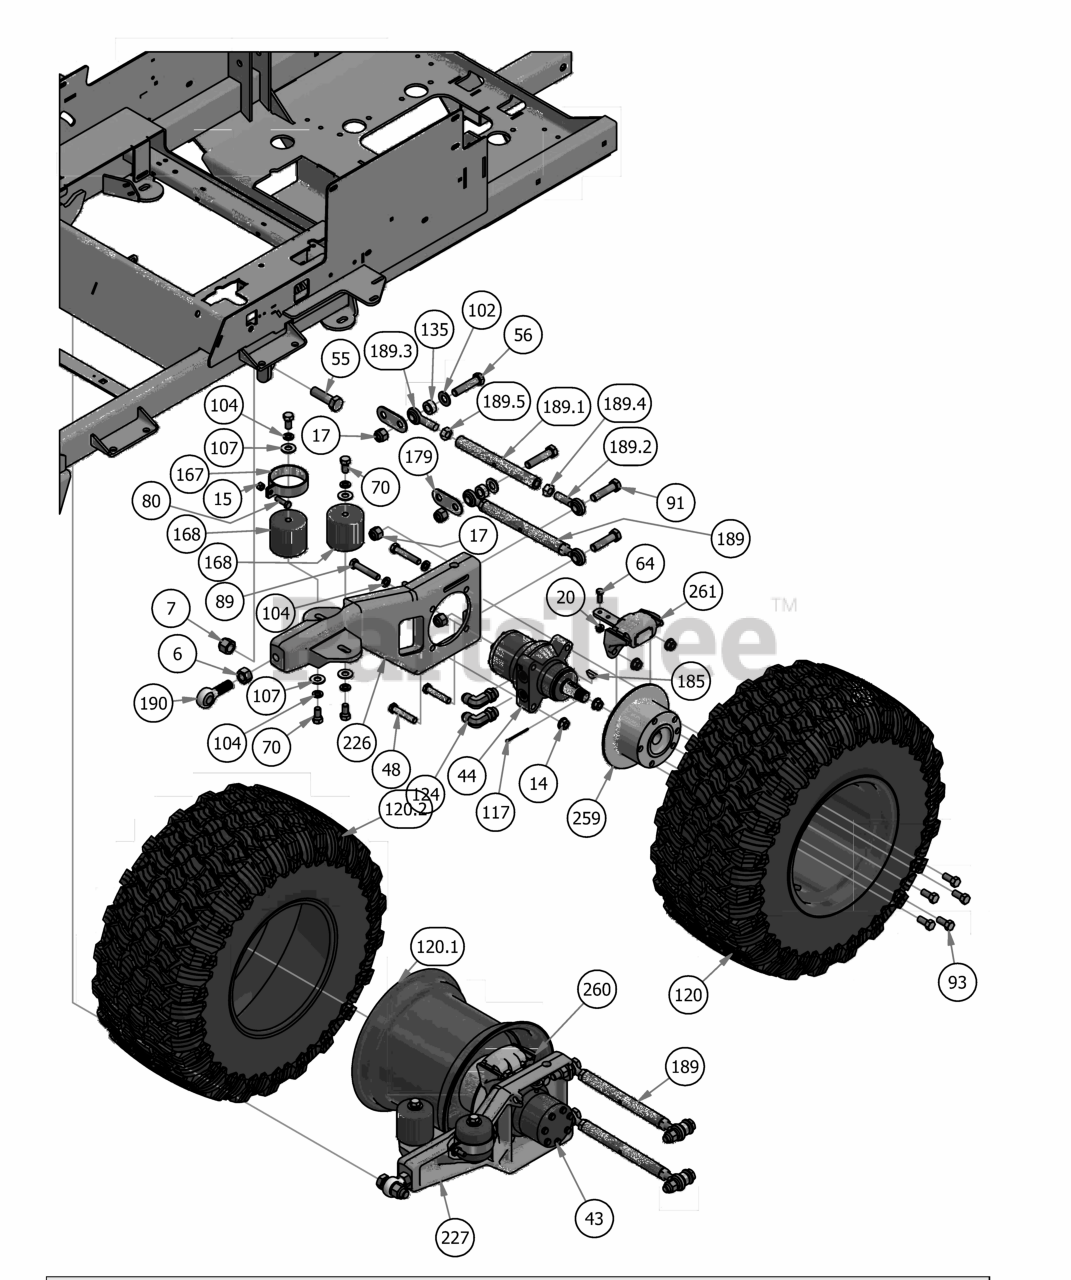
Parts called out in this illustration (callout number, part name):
6	3/4"-16 Fine Full Nut
7	3/4" Course Thread Nylon Lock Nut
14	1/2" Flange Nut
15	3/8" Hex Nut
17	5/8 Std NC Nylock Nut
20	5/16-18 Nylon Flange Nut
43	18ci Parker Wheel Motor-Right
44	18ci Parker Wheel Motor - Left
48	1/2" x 3" Hex Bolt
55	3/4 x 2 1/2 Course Thread Bolt
56	AS 2465 - 5/8 x 2 3/4 UNC
64	5/16" x 1" Bolt
70	1/2" x 1" Hex Bolt
80	3/8" x 1 1/4" Hex Bolt
89	1/2" x 2 3/4" Hex Bolt
91	5/8" x 2 1/2" Grade 5 Hex Bolt (Coarse)
93	1/2-20 x 1-1/2 Lug Bolts Zinc
102	5/8" Flat Washer SAE Spec Grade 8
104	1/2" Lock Washer
107	1/2" Washer (Grade 8)
117	1/8x2-1/4 cotter pin Zinc
120	2019 Assy-26x12-12 Reaper Turf 2019-10.5" Rim
120.1	2019 10.5" Wheel
120.2	2019 26x12-12 Reaper Turf Tire
124	2019 Rouge/Renegade Wheel Motor 90* Fitting #6801-10L
135	5/8" x 1/" Collar W/One Set Screw
167	2019 Bad Boy Max Iso-Band
168	Vibration Mount-Blue Dot
179	2019 Suspension Gusset Outlaw
185	Woodruff Key
189	2019 Suspension Radius Rod Assembly
189.1	2019 Suspension Link Body
189.2	2019 RH 5/8" Heim
189.3	2019 LH 5/8" Heim
189.4	Nut, 5/8-18 RH
189.5	Nut, 5/8-18 LH
190	3/4-16 RH Male Rod End
226	2019 Left Trailing Arm
227	2019 Right Trailing Arm
230	2019 Horizontal Diesel Frame
259	Brake Disk
260	XP/AOS Right Brake Caliper
261	XP/AOS Left Brake Caliper
